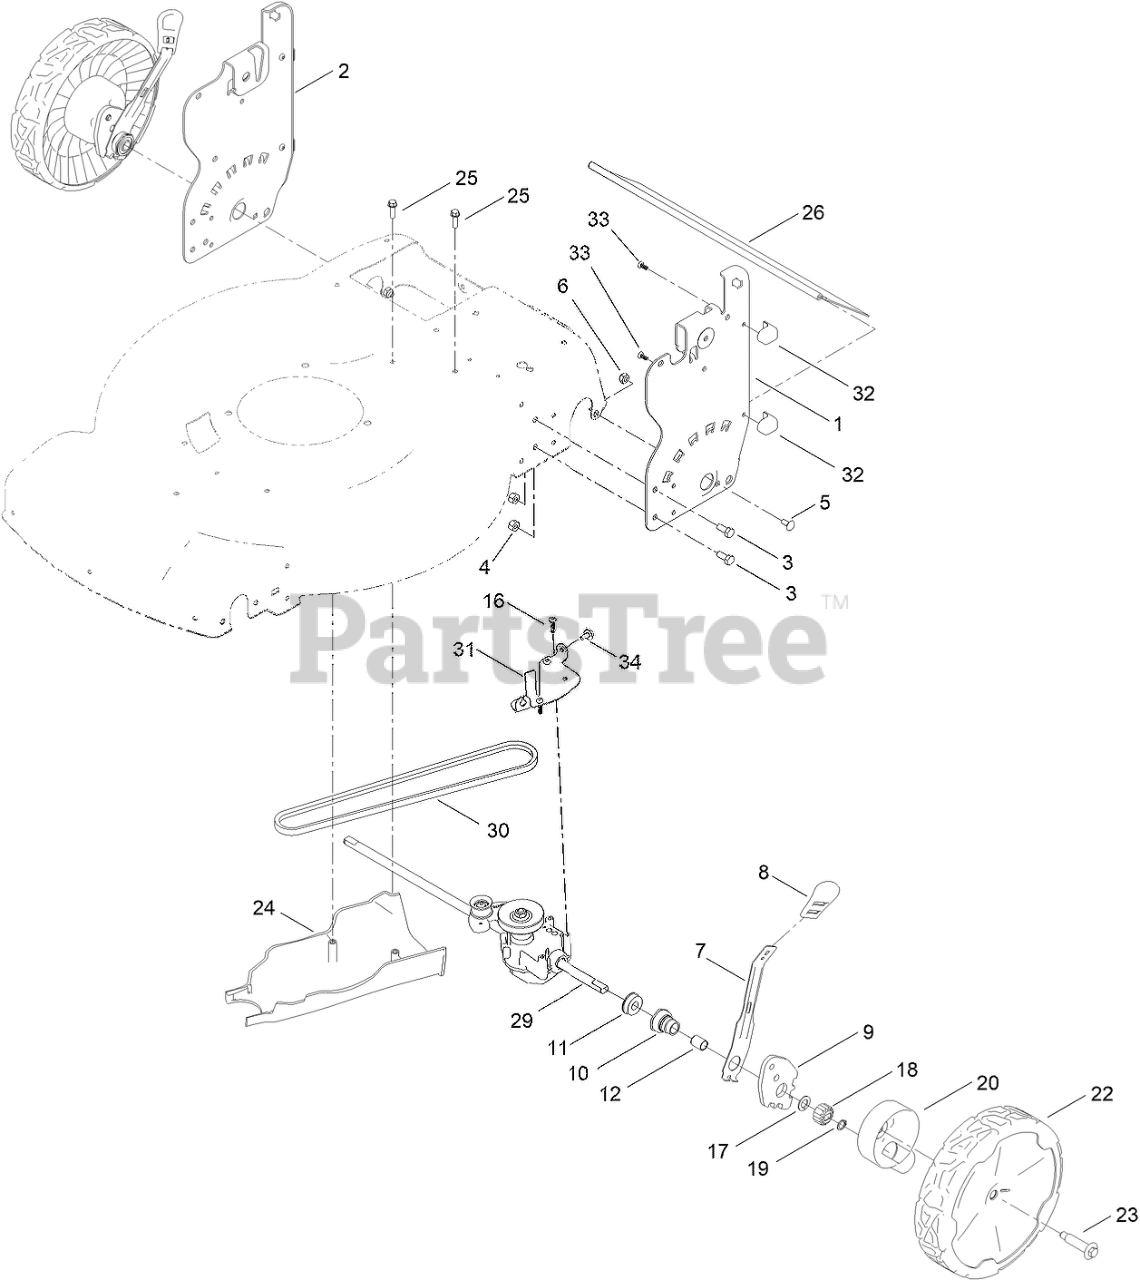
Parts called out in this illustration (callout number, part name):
1	PLATE-HOC, LH (2 HOLE)
2	PLATE-HOC, RH (2 HOLE)
3	SCREW-HH
4	NUT-HEX
5	BOLT-CARR
6	NUT-LOCK
7	ARM-SPRING
8	KNOB-HOC
9	ARM-PIVOT, REAR
10	RETAINER-BUSHING, HOC
11	BEARING-BALL
12	BUSHING-SLEEVE
16	SCREW-PLASTITE
17	WASHER-THRUST
18	GEAR-PINION, 15T
19	RING-RETAINING
20	ASM-COVER, GEAR (DK GRAY)
22	ASM-9.65" WHEEL, GEARED
23	WHEEL BOLT
24	COVER-BELT, REAR
25	SCREW-PLASTITE, HWH
26	SHIELD-TRAILING
29	TRANSMISSION-AWD
30	BELT-AWD, 34.50
31	GUIDE-BELT, AWD
32	PAD-SMART STOW
33	SCREW-PPH
34	SCREW-HWH, THD ROLL
